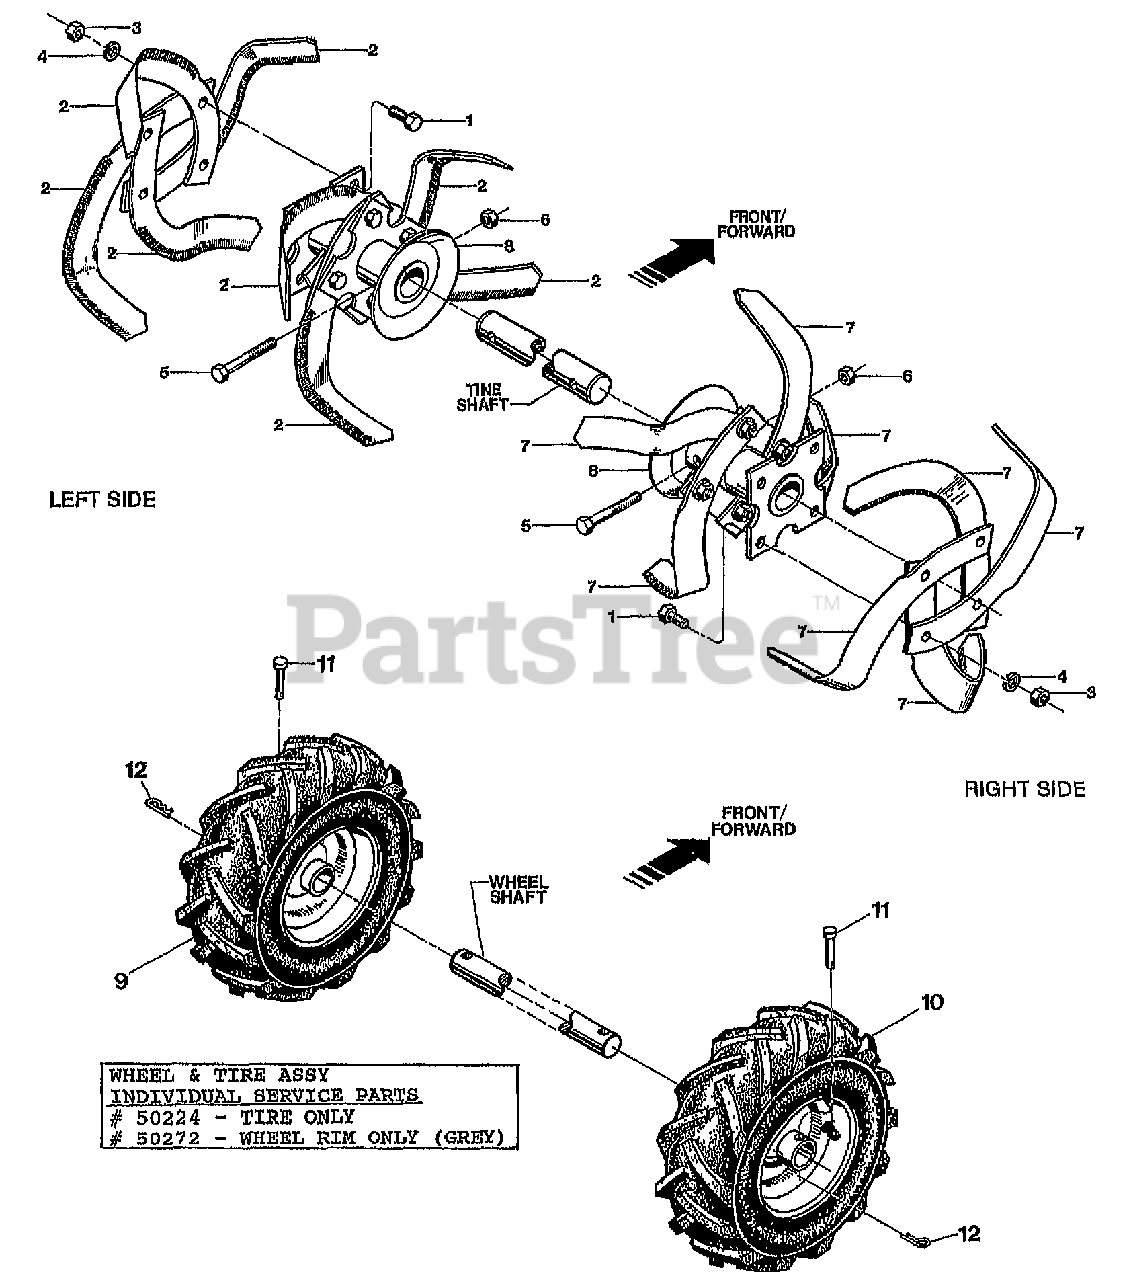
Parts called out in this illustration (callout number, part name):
1	SCR-HH 3/8-16X1.0 G5 ZP
2	TINE-BOLO RIGHT
3	NUT-HEX 3/8-16 ZP
4	WASHER-LK .375 @ DEPL
5	SCR-HH 3/8-16X2.00 G8 (hldr to tllr shaft)
6	NUT-H/LK 3/8-16
7	TINE-BOLO LEFT
8	HOLDER-TINE JUNIOR (for bolo tines, lt & rt)
9	ASSM-WHEEL&TIRE LT
10	ASSM-WHEEL&TIRE RT
11	PIN-CLEVIS (SECUR WHEEL HUB TO WHEEL SHAFT)
12	PIN-CLIP .08
